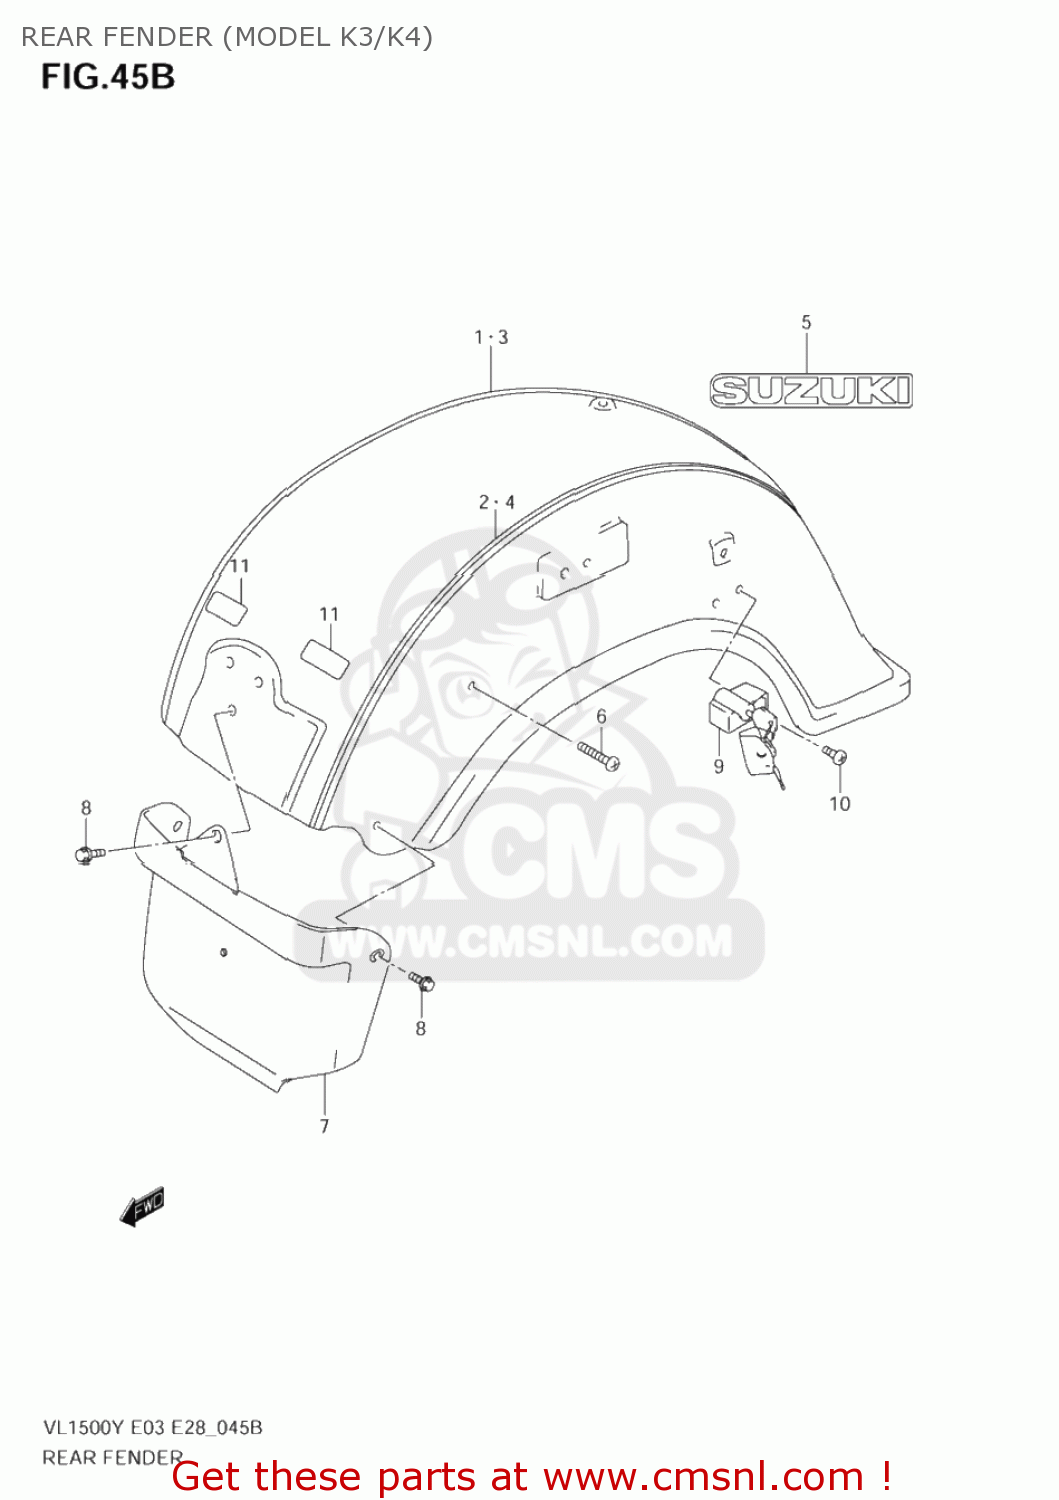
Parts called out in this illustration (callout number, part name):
1	FENDER ASSY,RR
2	TAPE SET,RR FENDER
3	FENDER, REAR
4	TAPE SET,RR FENDER
5	EMBLEM
6	BOLT(8X37)
7	MUDGUARD,RR FENDER FR
8	BOLT(6X16)
9	LOCK SET,HELMET
10	SCREW(6X14)
11	TAPE,RR FENDER
